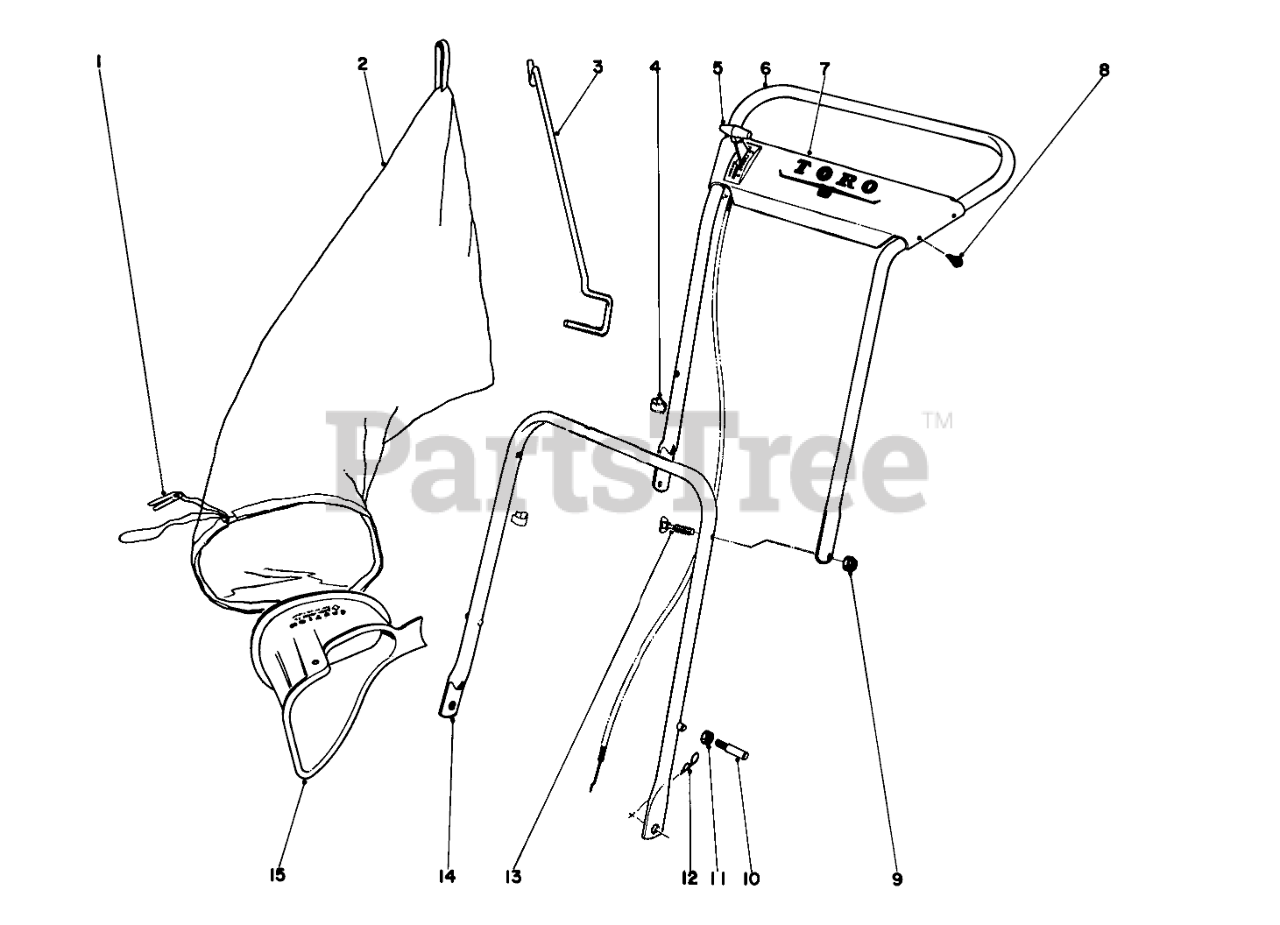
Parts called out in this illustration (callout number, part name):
1	BAG CORD FASTENER
2	Grass Bag Kit (2 Bags) (Incl. Ref. No. 1)
3	Bag Hanger Rod
4	CONTROL WIRE CLIP
5	Throttle Control
6	Upper Handle
7	Escutcheon
8	SCREW-HWHTF
9	Nut
10	Handle Pin
11	Nut
12	PIN-COTTER, HAIR
13	1-1/4 LG HANDLE SCREW
14	Lower Handle
15	BAG ATTACHMENT
